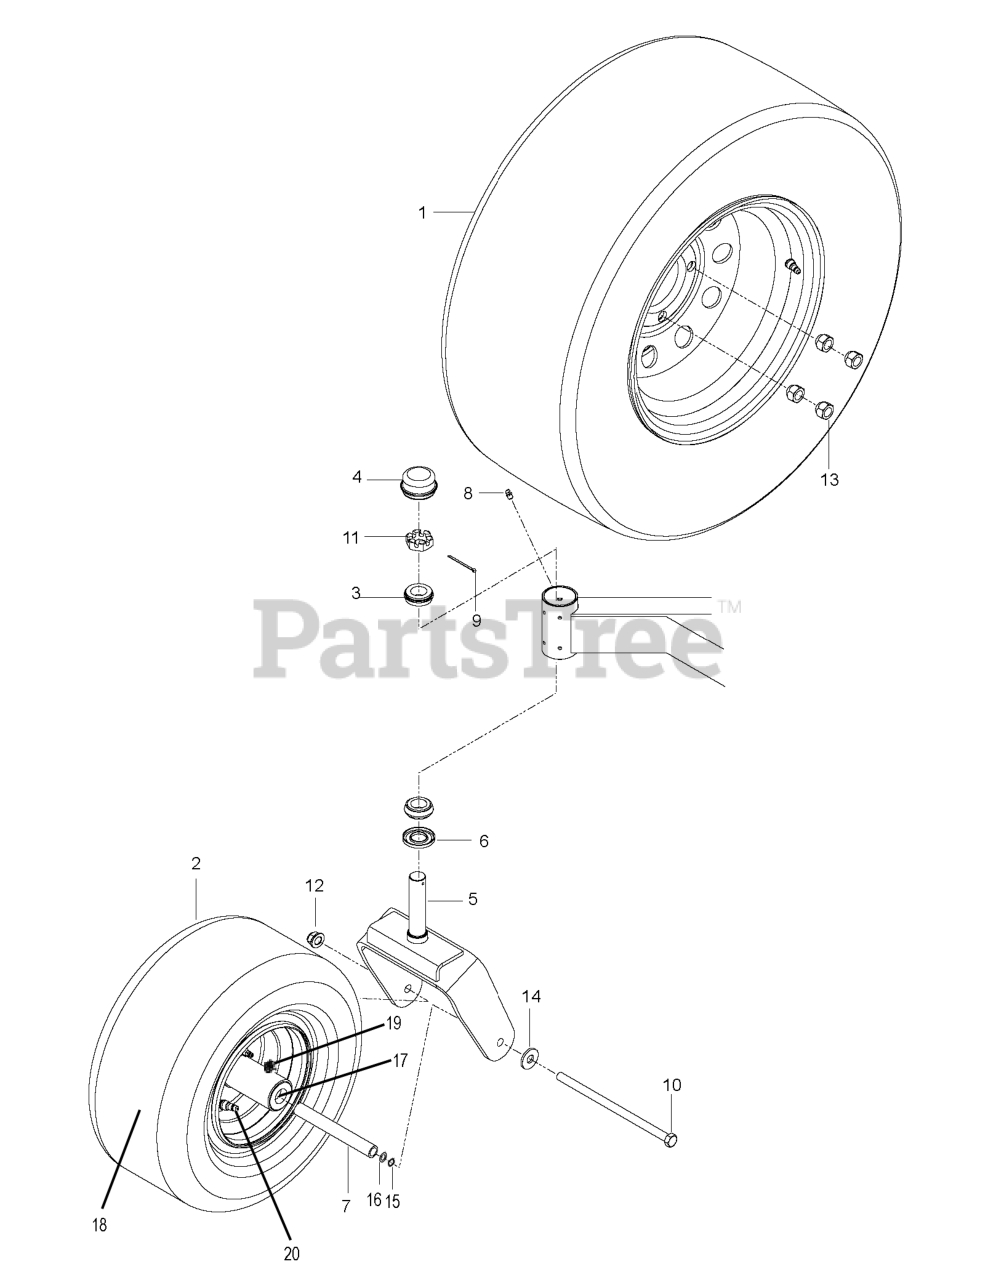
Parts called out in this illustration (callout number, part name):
1	WHEEL.ASSEM.22X10-10.SILVE.ZTR
2	TIRE.ASSEM.CASTER.13X6.5-6.SIL
3	TAPERED ROLLER BRG
4	GREASE CAP
4	Caps
5	FORK.CASTER.ASM.PNT.668
7	SPACER, PIVOT
8	ZERK
9	Pins
9	COTTER PIN 1/8 X 2
10	GSPW Screws
10	HEX SCREW 1/2-13 X 9.5 GR5
11	Nuts
11	NUT 1"C HEX SLOTTED
12	NUT, 1/2-13 HEX FLG NYLOC ZD
13	NUT.1/2-20.UNF-2B.GR.8.YL
13	LUG NUT 1/2F
14	Washers
14	WASHER.9/16 X 1 3/8 X 12 GA.
15	WASHER, .825 X 1.087, WAVE
16	Shims
17	ROLLER BEARING-CAGED 3 1/4'
17	BEARING RETAINER
18	TIRE - SMOOTH 13X6.50-6
19	ZERK
